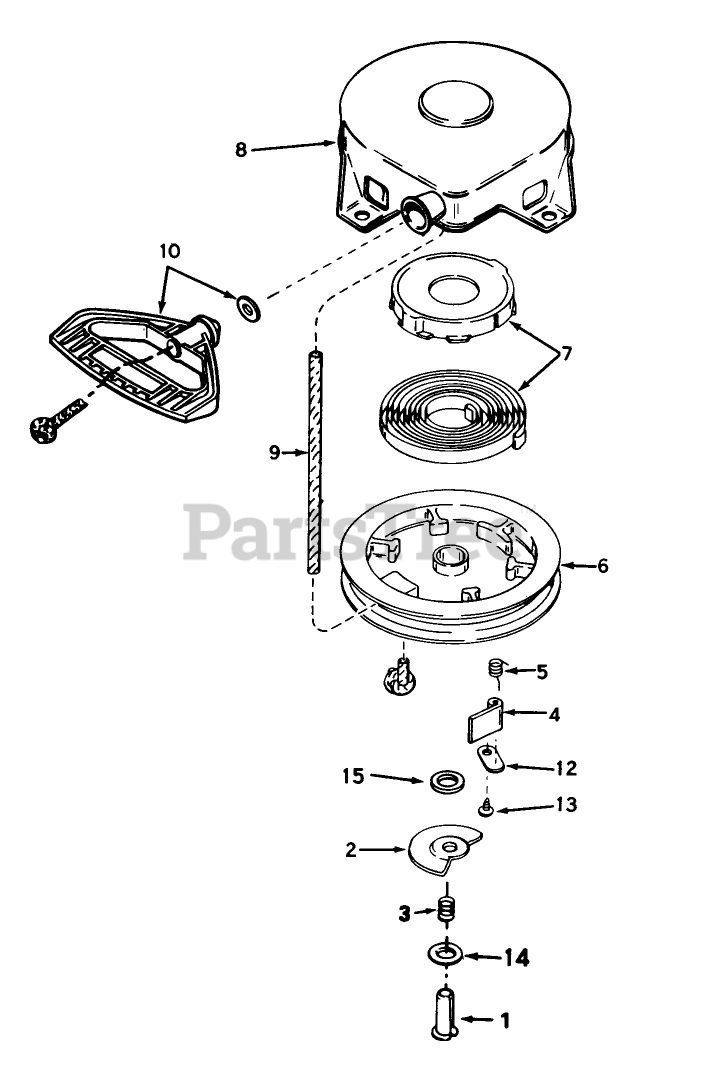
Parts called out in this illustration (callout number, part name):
1	Pin Spring
2	Washer
3	Brake Spring
4	Dog-Starter
5	Spring-Dog
6	Pulley
7	Spring Keeper Assy
8	Housing-Starter
9	Rope-Starter
10	Handle-Starter, Mitten Grip
12	Retainer-Dog
13	Screw
14	Washer
15	Washer
